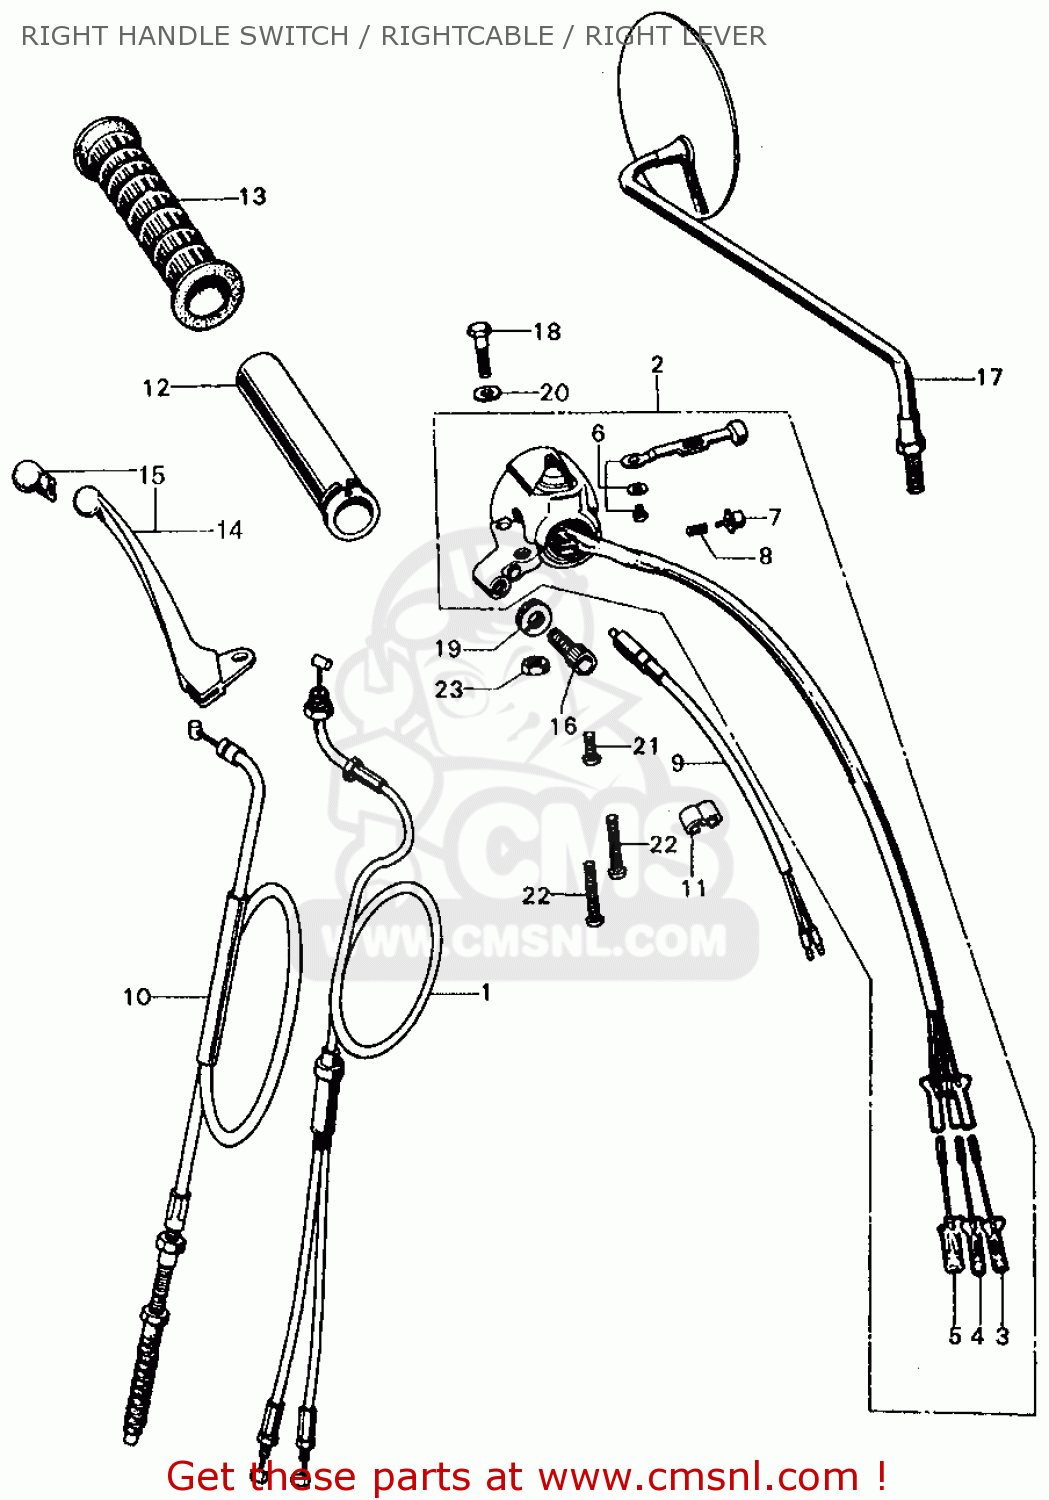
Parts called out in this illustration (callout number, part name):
1	CABLE,THROTTLE
2	SWITCH START KILL
3	CORD A,STATERKILL
4	CORD B,STATERKILL
5	SUB-CORD C,KILL
6	KNOB,DIMMER SW.
7	BUTTUN, HORN
8	SPRING,
9	SWITCH,FR.STOP
10	CABLE,FR.BRAKE
11	CLIP, BRAKE WIRE
12	PIPE A,GRIP
13	GLIP,R HANDLE
14	LEVER,R
15	CAP LEVER
16	BOLT
17	MIRROR,R BACK
18	BOLT,PIVOT
19	NUT,FIXING
20	WASHER,7X12
21	SCREW,CROSS 5X6
22	SCREW,PAN,5X25
23	NUT HEX 6MM
